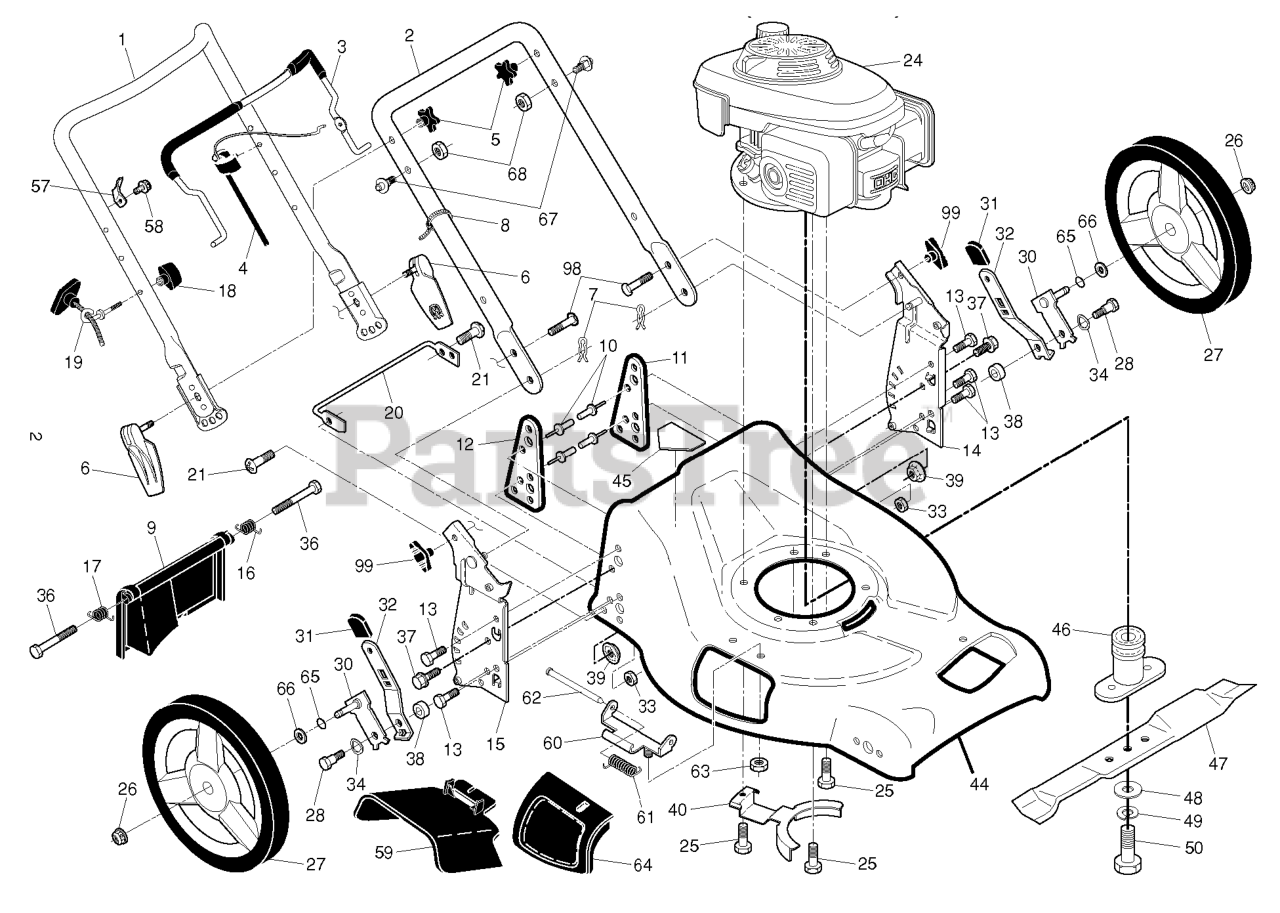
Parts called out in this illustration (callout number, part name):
1	HANDLE.ASM.UP.W/ADJ.BKT.21FGD
2	HANDLE.LOWER.21.NB.GREY
3	BAIL.OVER.MOLD.ERGO.MZR.ORANGE
4	CABLE.ASM.ZONE.CONTROL
5	KNOB.HANDLE.PLASTIC.STAR.BLACK
6	QUICK.ASM.RELEASE.BLACK
7	HAIRPIN COTTER
8	TIE GUIDE
9	DOOR.REAR.PLASTIC.21.FWGD.498
10	RIVET BLIND
11	SUPPORT BRACKET LH
12	BRACKET.SUPRT.RH.21.FWGD
13	SCREW 14-20 X 5/8
14	BRACKET.ASM.HDL.LT.21FGD.HW.NB
15	BRACKET.ASM.HDL.RT.21FD.HW.NB
16	SPRING.REAR.DOOR.EZ.21.LT
17	SPRING.REAR.DOOR.EZ.21.RT
18	T-KNOB.NEW ROPE GUIDE
19	GUIDE.ROPE.BLK.ZINC.CHROM
20	FOOT.GUARD.21.DOM/FGD.CE.10
21	SCREW
25	BOLT 3/8-16X1-1/8
26	NUT.HEX.FLANGE.3/8-16.LOCKNUT
27	WHEEL.12 X 1.75 CFH3SPK.RAD3
28	SHOULDER BOLT 5/16-18
30	ARM.ASM.AXLE.REAR.5/9.POS.BZP
31	SELECTOR KNOB
32	SELECTOR SPRING
33	NUT.71038.31-18.HEX.NYLOCK
34	WASHER.CURVED.CYLINDRICAL
37	BOLT.FIN.HEX.5/16-18X3/4
38	SPACER.HEIGHT.ADJUSTER
39	NUT.FLANGE.5/16
40	BRACKET.ENG/BELTKEEPER
44	KIT.HSG.21.FGD.MC.ORG.CE SYM
45	DECAL.INTERNATIONL.CUTFINGER
46	RB ADAPTER.BLADE.25MM.VS.LOW
47	BLADE.21.PUSH
48	WASHER,HARDEN
49	LOCKWASHER
50	SCREW, HEX HD 3/8-24 X 1-3/8
57	BRACKET.UPSTOP.RT
59	DEFLECTOR.CLIPPIN.21.FGD
60	BRACKET.ASM.HINGE.21.FWGD.
61	SPRING.TORSION
62	ROD.HINGE.21
63	LOCKNUT.NYLOC.1/4-20
64	DOOR.MULCH.21.REAR.FWGD
65	O-RING..070X.487.NEOPRENE
66	WASHER.FLAT.1/2
67	STUD.QUICK.ADJUST
68	NUT.LOCK.5/16-18
98	BOLT.CARRIAGE.LN.5/16-18X.5/8
99	KNOB, DEFLECTOR
